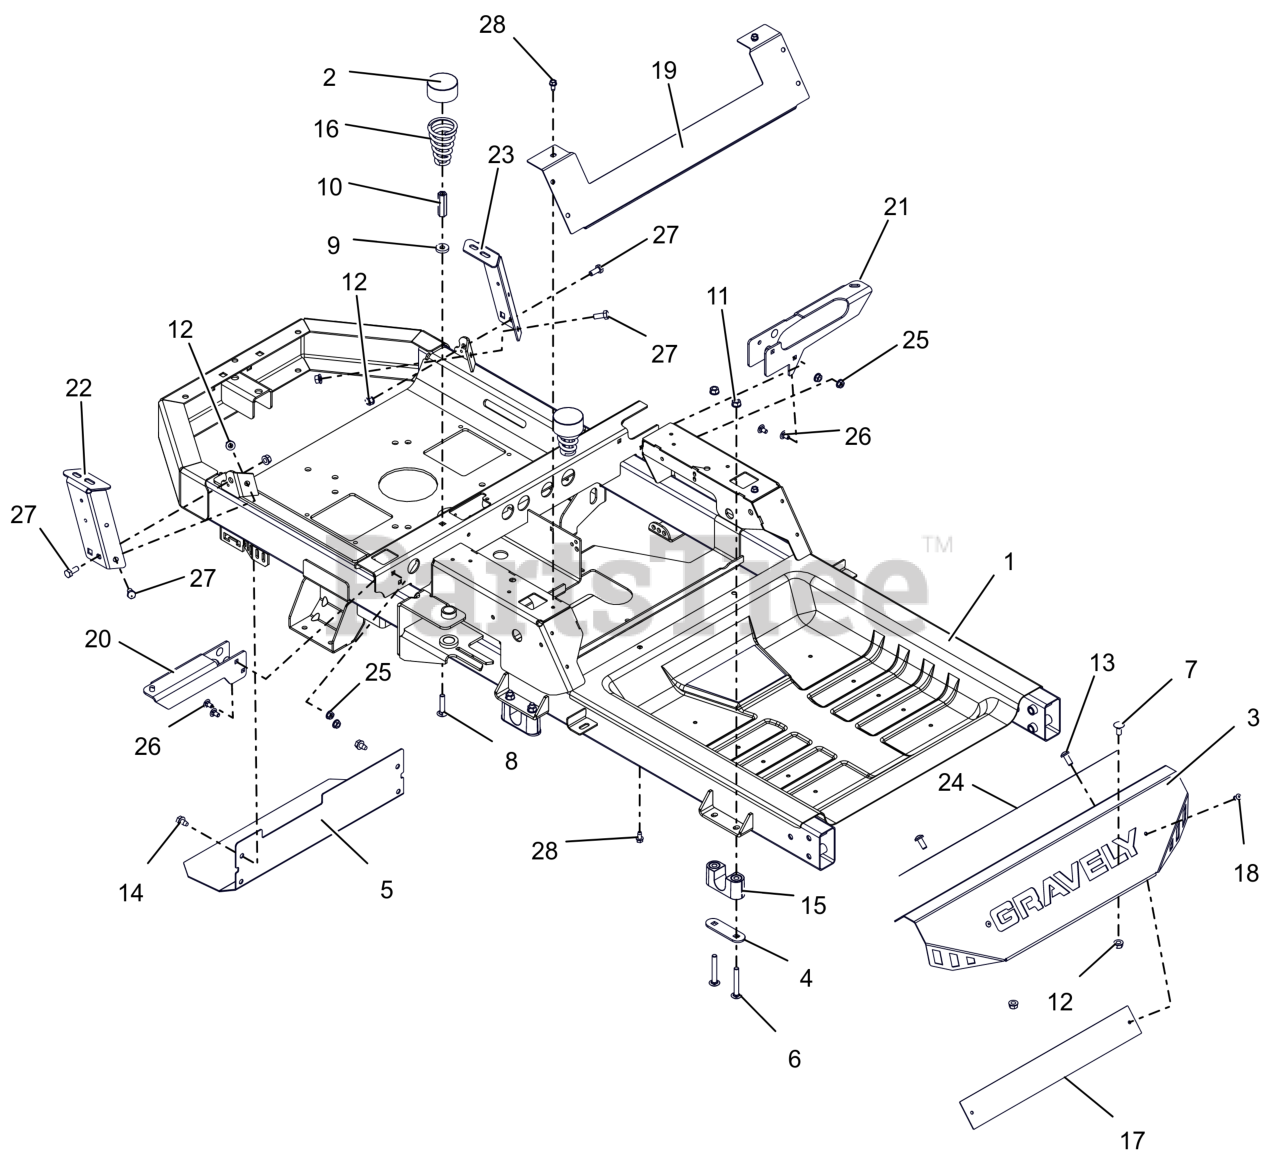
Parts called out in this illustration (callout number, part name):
1	KIT, ZT-X/XL FRAME SERVICE
3	KIT, FOOTPLATE W/DECAL-ZTX
4	PLATE, BEARING SUPPORT
5	HEAT, SHIELD
6	BLT, RHSSN.31-18X2.25 G5 ZCC
7	BLT,RHSN .31-18X.75 G5 ZCC
8	BLT,RHSN .31-18X1.50 G5 ZCC
9	WSHR, FLT .328X.870X.179 ZCC
10	NUT, COUPLING .31-18X1.75 ZCC
11	NUT,LK-CTR-FLG .31-18 GF ZCC
12	NUT-LK-TOP-FLG .312-18 GF ZCC
13	SCR-RDHDSKTAP .31-18X.75
14	SCR,TAP .312-18X.50 HWH TR ZCC
15	BSHG, DECK LIFT PIVOT
16	SPRING, SEAT
17	PLATE, BACK FOOT-REST XL
18	RIVET, #66 STEEL POP PD BLACK
19	PLATE, SEAT KICK
20	BRKT,CROSS EXTENSION - LH
21	BRKT,CROSS EXTENSTION - RH
22	MOUNT,FENDER-RH EXTENSION
23	MOUNT,FENDER-LH EXTENSION
24	GRIP, FOOT PLATE
25	NUT-LK-CTR-FLG .25-20 ZC120
26	BLT, RHSSN.25-20X.500 G5 ZCC
27	BLT,HEX .31-18X.75 G5 ZCC
28	SCR-TAP .25-20X.50 HWH ZCC
